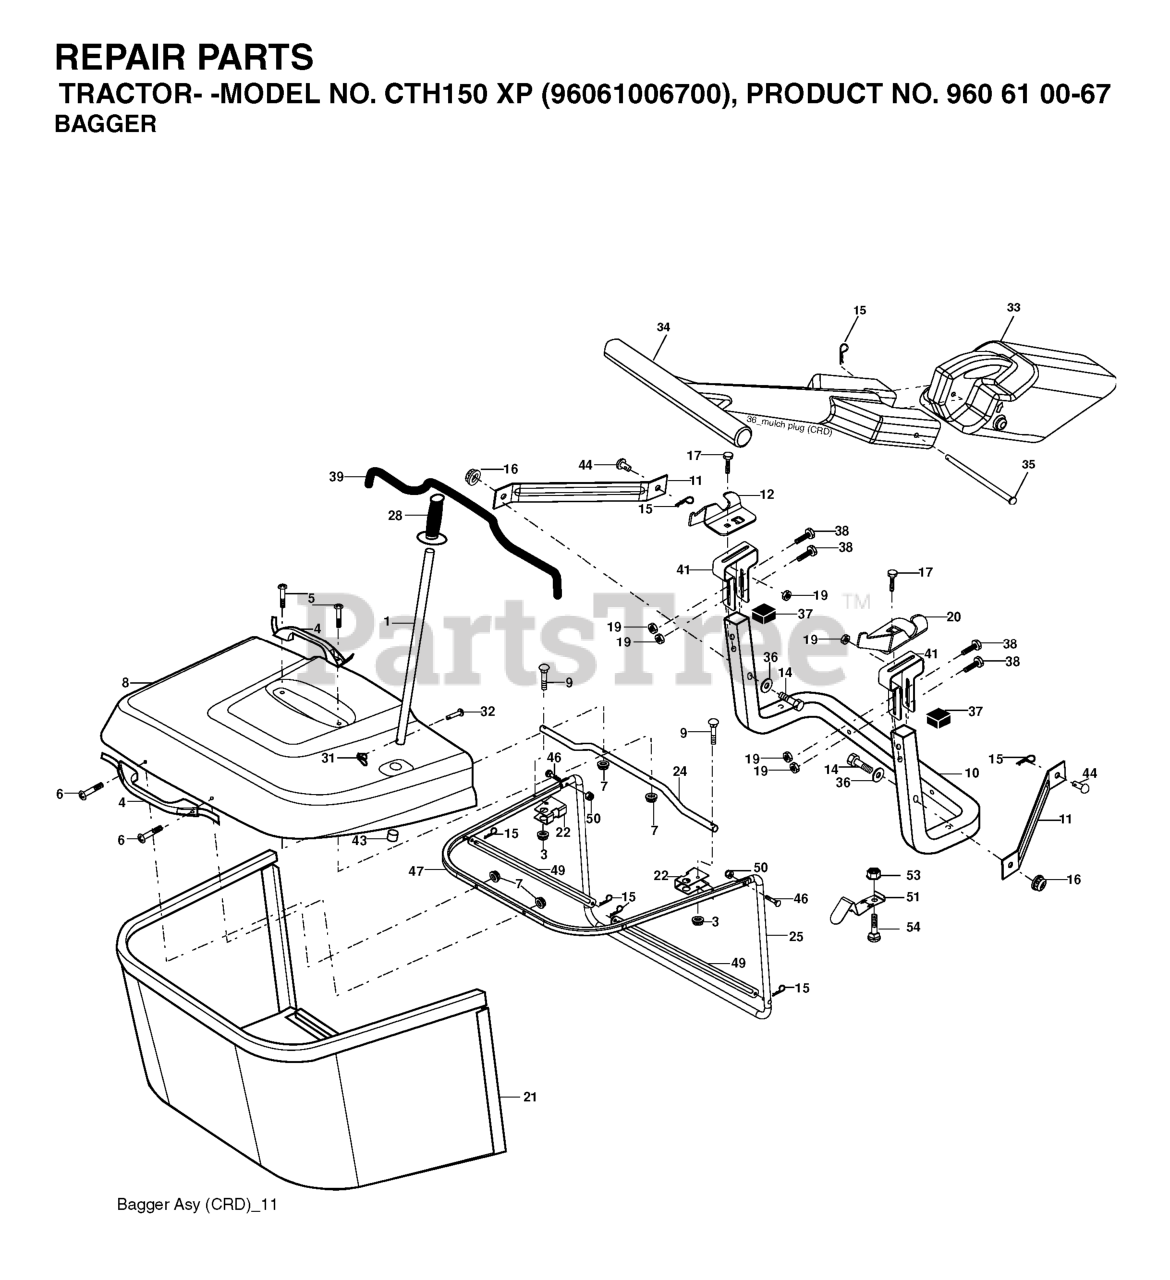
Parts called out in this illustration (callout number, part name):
1	TUBE HANDLE
3	NUT T
4	HANDLE.BAGGER.W/LVRS.BLK.CRD
5	SCREW.PAN.HEAD
6	REPL BY 532 75 00-29
8	COVER.PNT.BGR.CRD.WSLOTS.MS668
9	Bolt Carriage 1/4-20 x 2.25d x Gr.5
10	TUBE
11	BRACKET.SUPPORT.UPPER.BAG.CRD
12	BRKT PIVOT
14	BOLT-HEX EAK
15	RETAINER-SPRNG RB
16	NUT LOCK FLG 3/8-16 UNC
17	RP BOLT 5/16-18 X3/4 ZN/YEL GR
19	NUT LOCK HEX FLANGE 5/16-18
20	BRKT.PIVOT.RH.CRD
22	BRKT.SIDE.BAG.CRD
24	TUBE.PIVOT.BAG.CRD.BLACK
25	PIPE
28	GRIP.HANDLE.BLACK
31	RETAINER CLIP
32	RIVET,DRILLED
33	MULCH PLUG, CTH150
34	HANDLE.MULCHER.92.CRD (2 2)
36	WASHER
37	Plug Support Bagger CRD
38	BOLT.5/16-18X2.5
39	SEAL.TRIM.37'
41	BRKT.VERT.ADJ.BAGGER.CRD
43	PLUG, TUBING END
46	BOLT.CARRIAGE.5/16-18
47	PIPE
49	ROD
50	NUT.71038.31-18.HEX.NYLOCK
51	LATCH
53	NUT
54	BOLT
